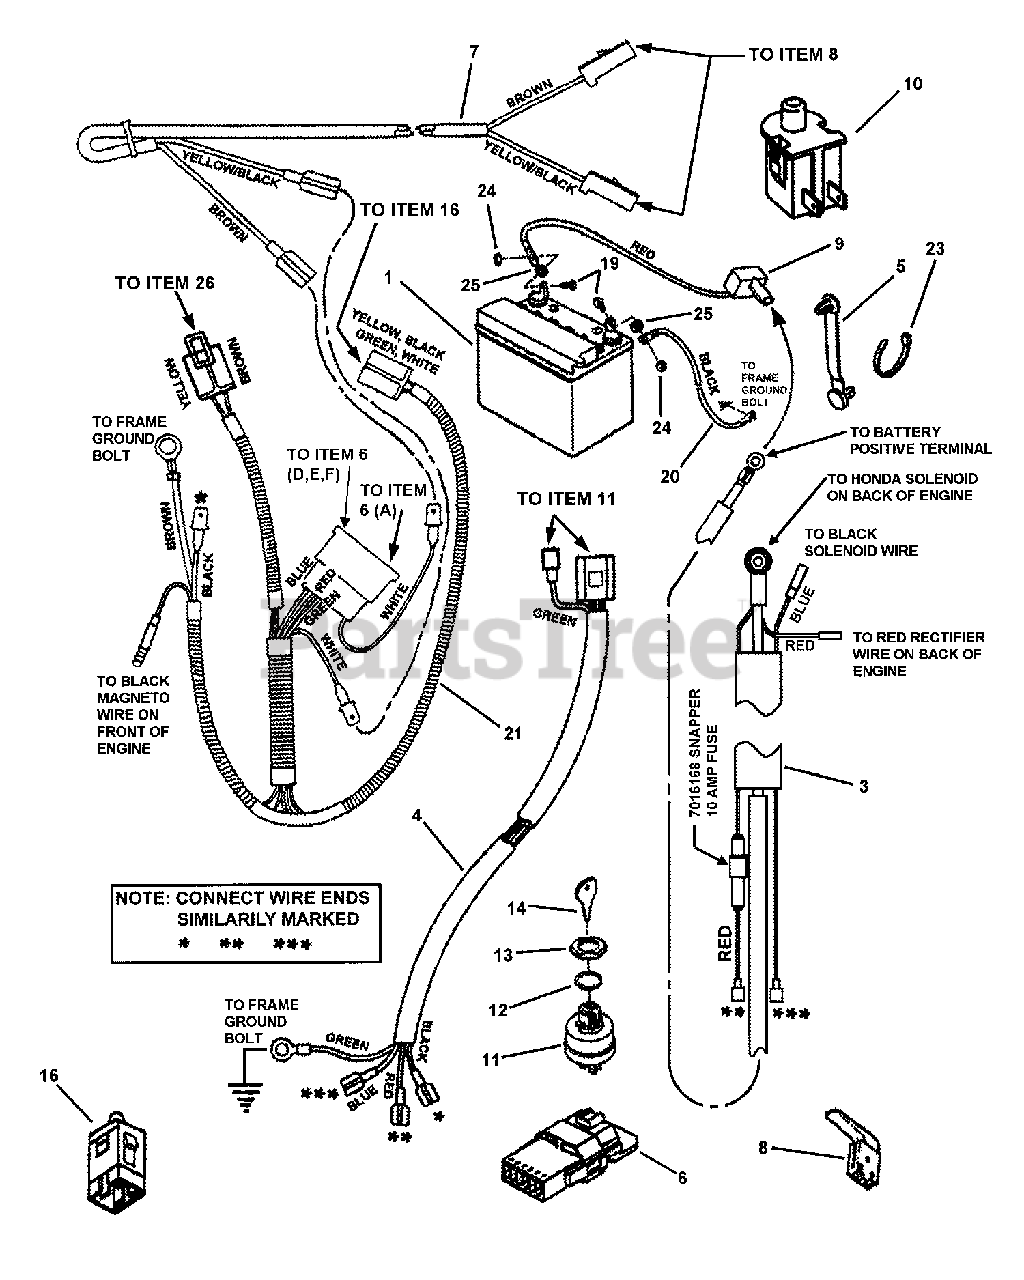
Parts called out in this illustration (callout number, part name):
1	KIT, 12V Dry Charge Battery
3	HARNESS, Starter Wiring (Honda)
4	HARNESS, Ignition Wiring
5	CABLE TIE, 3.19" long
6	INTERLOCK MODULE, Briggs & Kohler
7	HARNESS (Deck Interlock Wiring)
8	SWITCH, Deck Interlock (NO)
9	COVER, Battery Cable
10	SWITCH, Seat (NC)
11	SWITCH, Ignition, 4 Terminal, Indak
12	WASHER, 5/8" Internal Tooth Lock
13	NUT, 5/8-32 Hex
14	IGNITION KEY, Pair
16	SWITCH, Operator Presence Control (OPC) Traction (NC/NO)
19	SCREW, 1/4-20 x 5/8" Hex Head Cap. GR 5
20	WIRE, Negative, Black (15" long)
21	HARNESS, Operator Presence Control (OPC) Wire
23	CABLE TIE, 7"
24	NUT, 1/4-20 Hex Center Lock, GR 5 or B
25	RETAINER, 1/4" Bolt
